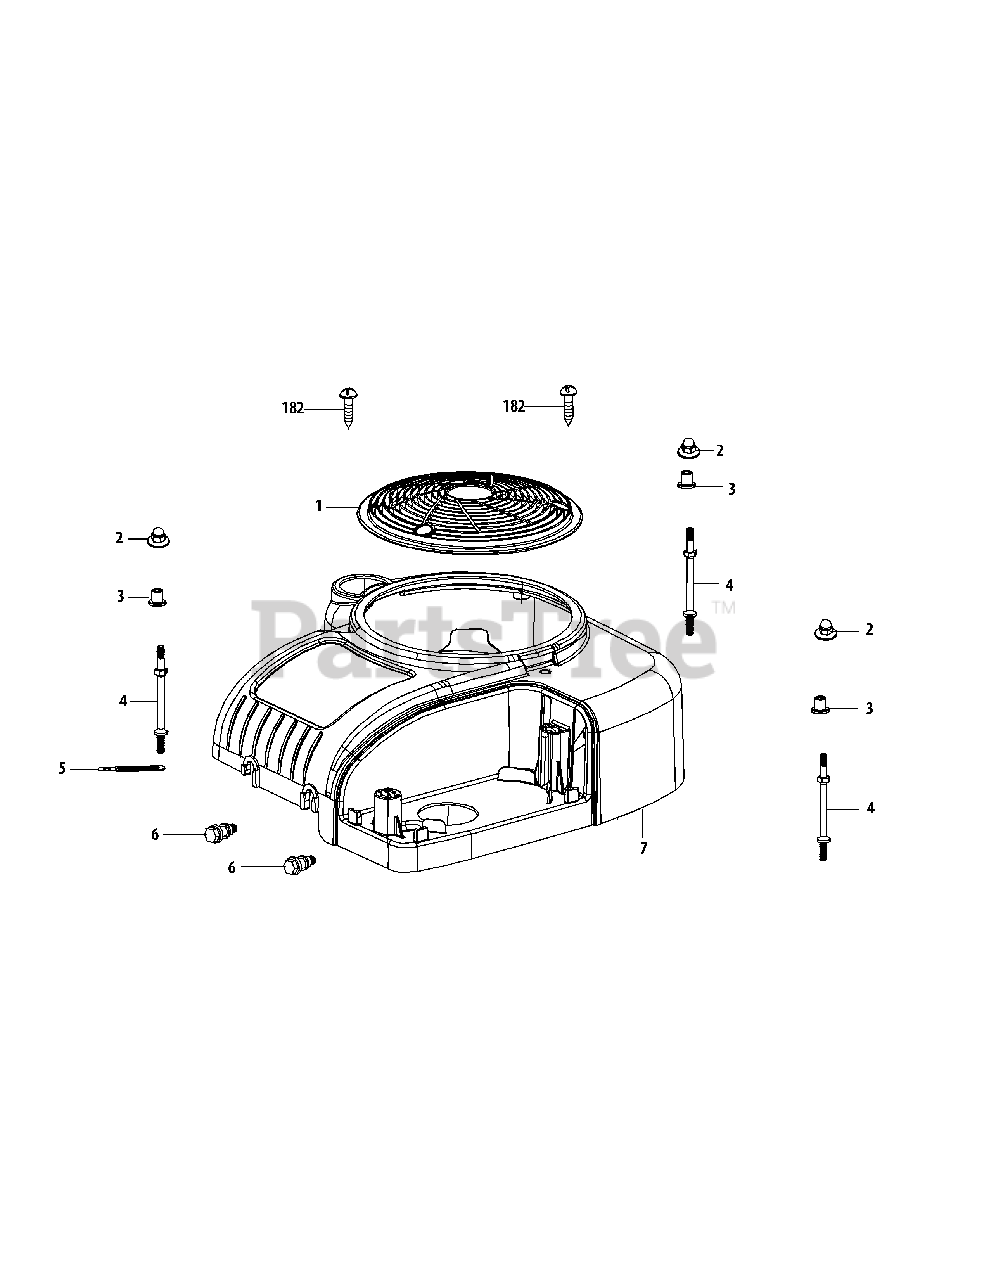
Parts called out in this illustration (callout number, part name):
1	Debris Shield
3	Engine Shroud Spacer
4	Starter / Shroud Stud M6×99
5	Flexible Clamp
6	Hook Bolt
7	Air Shield
182	Self-Tapping Bolt 5.5×25
